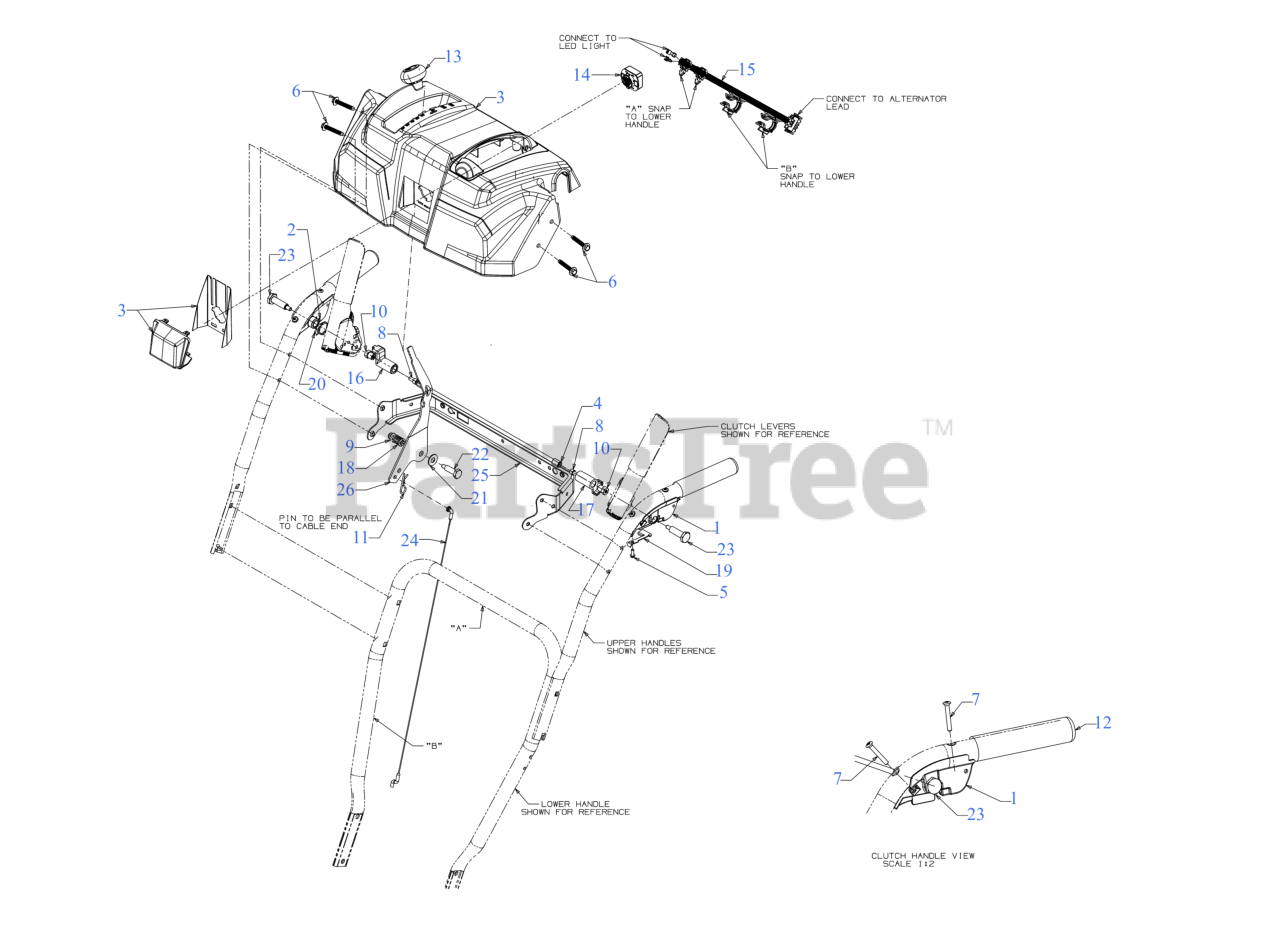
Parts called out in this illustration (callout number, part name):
1	CLUTCH LOCK HANDLE ASSEMBLY (LH)
2	CLUTCH LOCK HANDLE ASSEMBLY (RH)
3	HANDLE PANEL ASSEMBLY
3	LABEL:SNOW:2 STAGE
3	LENS
5	SCREW #8-16 x .50
6	SCREW 1/4-20 x 1.625
7	SCREW #10-24 x 1.375
8	SCREW 1/4-20 x .50
9	FLANGE LOCK NUT
10	HEX NUT W/PATCH
11	INTERNAL COTTER PIN
13	SHIFT KNOB
14	LED HEADLIGHT SOCKET (150 LUMNES)
15	LIGHT HARNESS
17	CLUTCH LOCK CAM
18	COMPRESSION SPRING
19	CLUTCH SPRING
20	TORSION SPRING
21	FLAT WASHER .40X.88X.060
22	SHOULDER SCREW
23	SHOULDER SCREW .437 x 1.345 1/4-20
24	SPEED SELECTOR CABLE (PLASTIC)
25	HANDLE SUPPORT BRACKET (POWDER BLACK)
